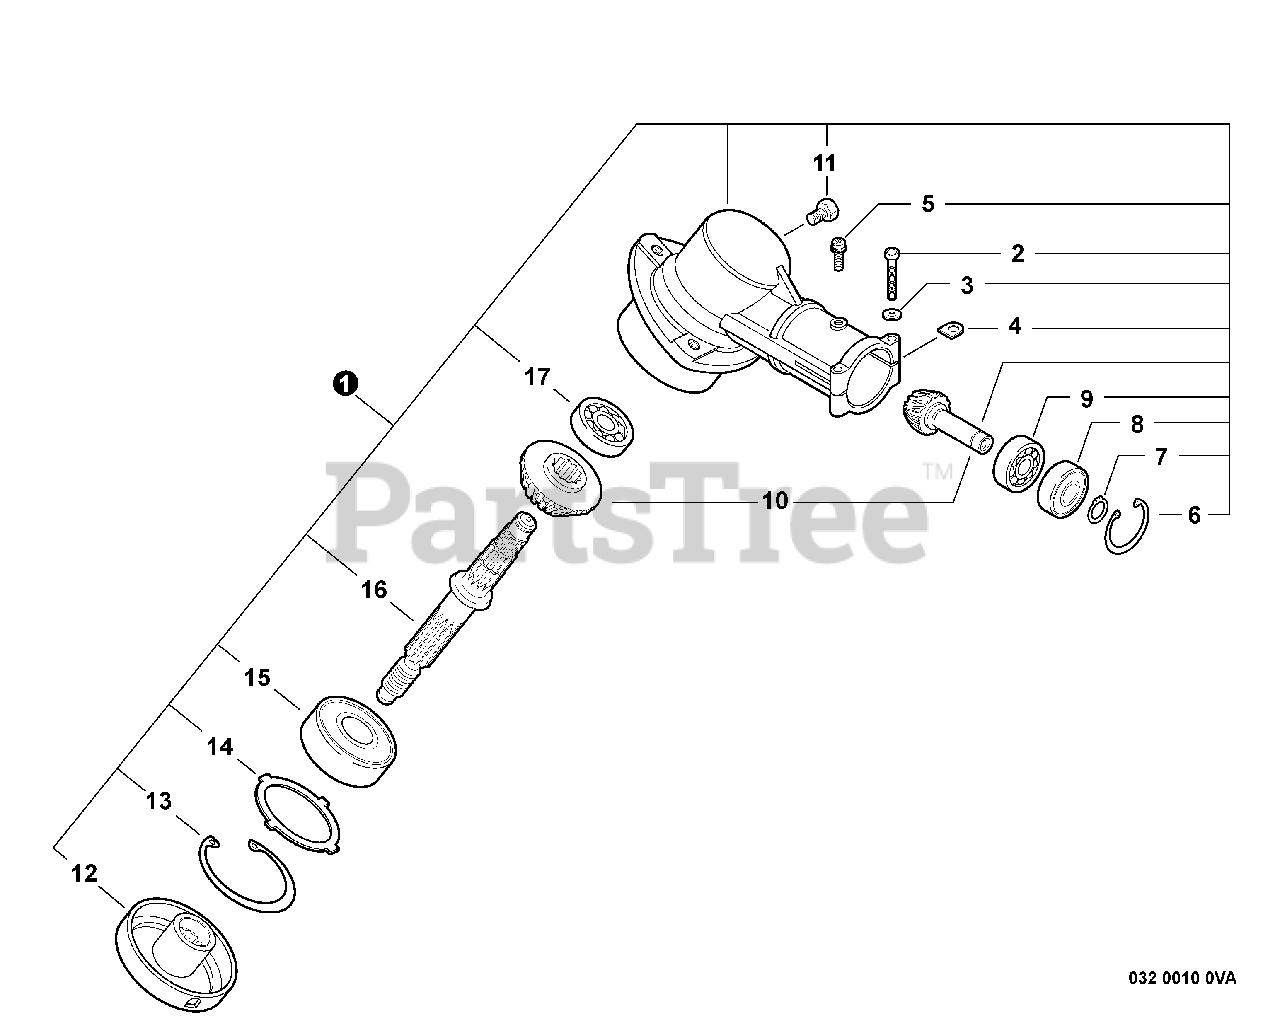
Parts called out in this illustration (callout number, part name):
1	GEAR CASE ASSY
2	BOLT 5×35 SP
3	WASHER, FLAT 5.5×10×0.8
5	SCREW 5×10
6	RING, SNAP Ø22
7	RING, SNAP Ø10
8	BEARING, BALL 6900Z
9	BEARING, BALL 6900
10	GEAR SET
11	BOLT M8×8
12	PLATE, ADAPTOR - UPPER
13	RING, SNAP Ø32
15	BEARING, BALL 6201
16	SHAFT, GEAR
17	BEARING, BALL 609
